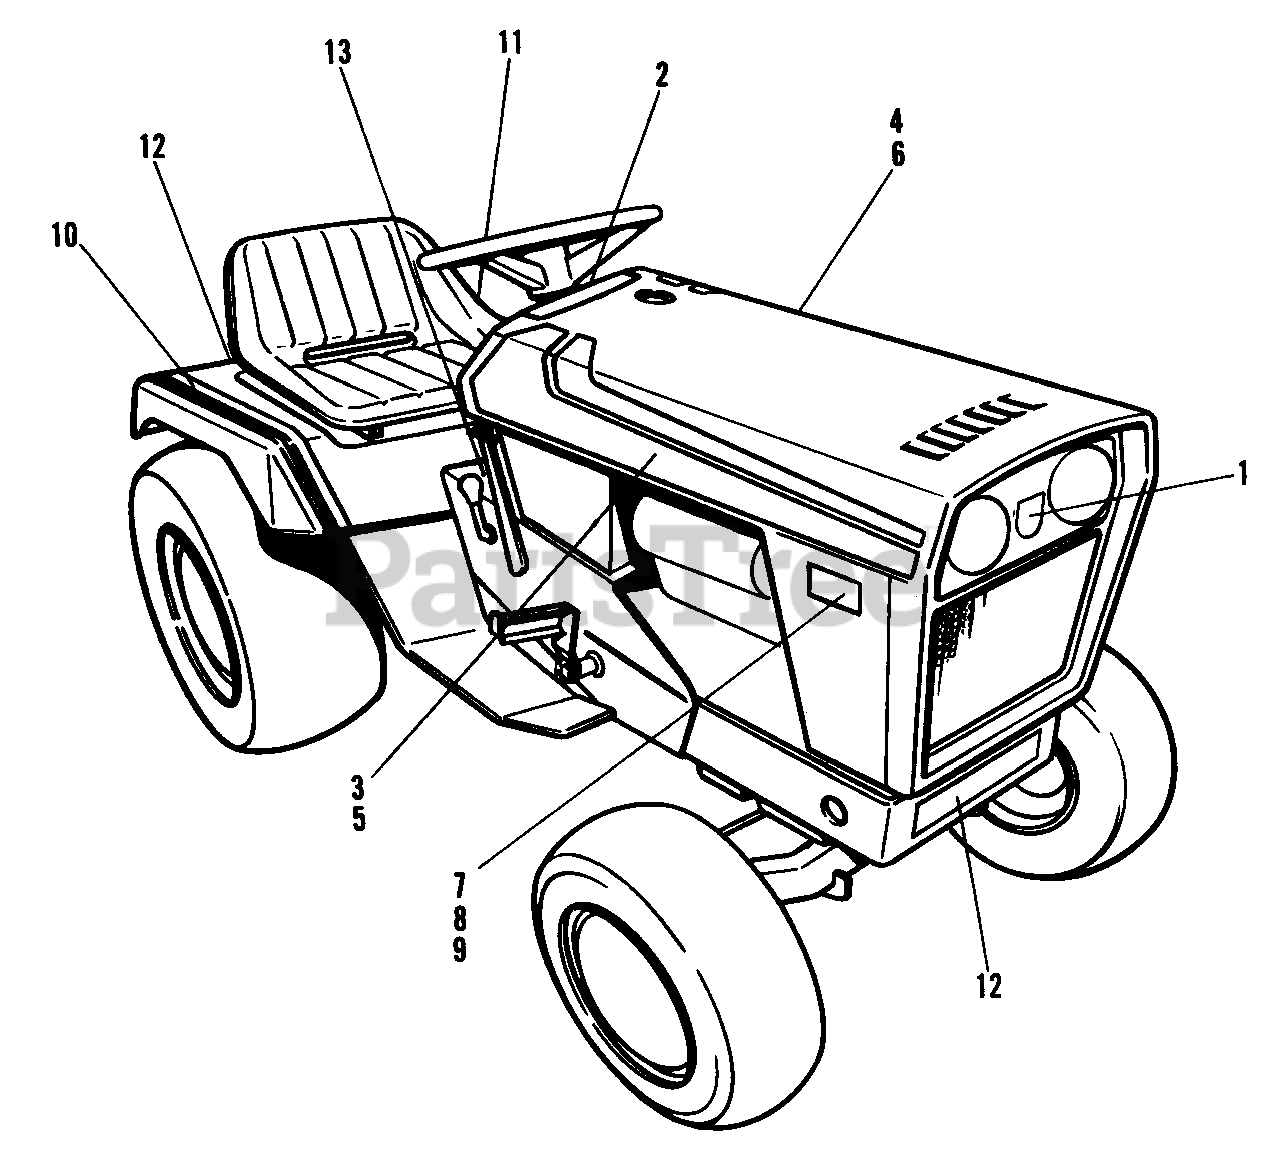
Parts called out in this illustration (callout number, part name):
1	DECAL, Simplicity Grille
2	DECAL, Dash, Hydro
3	DECAL, Hood, Landlord, R.H. (7112 Only)
4	DECAL, Hood, Landlord, L.H. (7112 Only)
5	DECAL, Hood, Sovereign, R.H. (7116 & 7117 Only)
6	DECAL, Hood Sovereign, L.H. (7116 & 7117 Only)
7	DECAL, 7112 Hydro
8	DECAL, 7116 Hydro
9	DECAL, 7117 Hydro
10	DECAL, Seat Deck, R.H.
11	DECAL, Seat Deck, L.H.
12	DECAL, Simplicity
13	DECAL, Console, Hydro
13	DECAL, Caution (on top of engine)
13	DECAL, Drive Belts (inside hood)
13	DECAL, Warning (under seat deck)
13	DECAL, Simplicity Twin 17 (7117 Only) (Mounted on side of engine)
